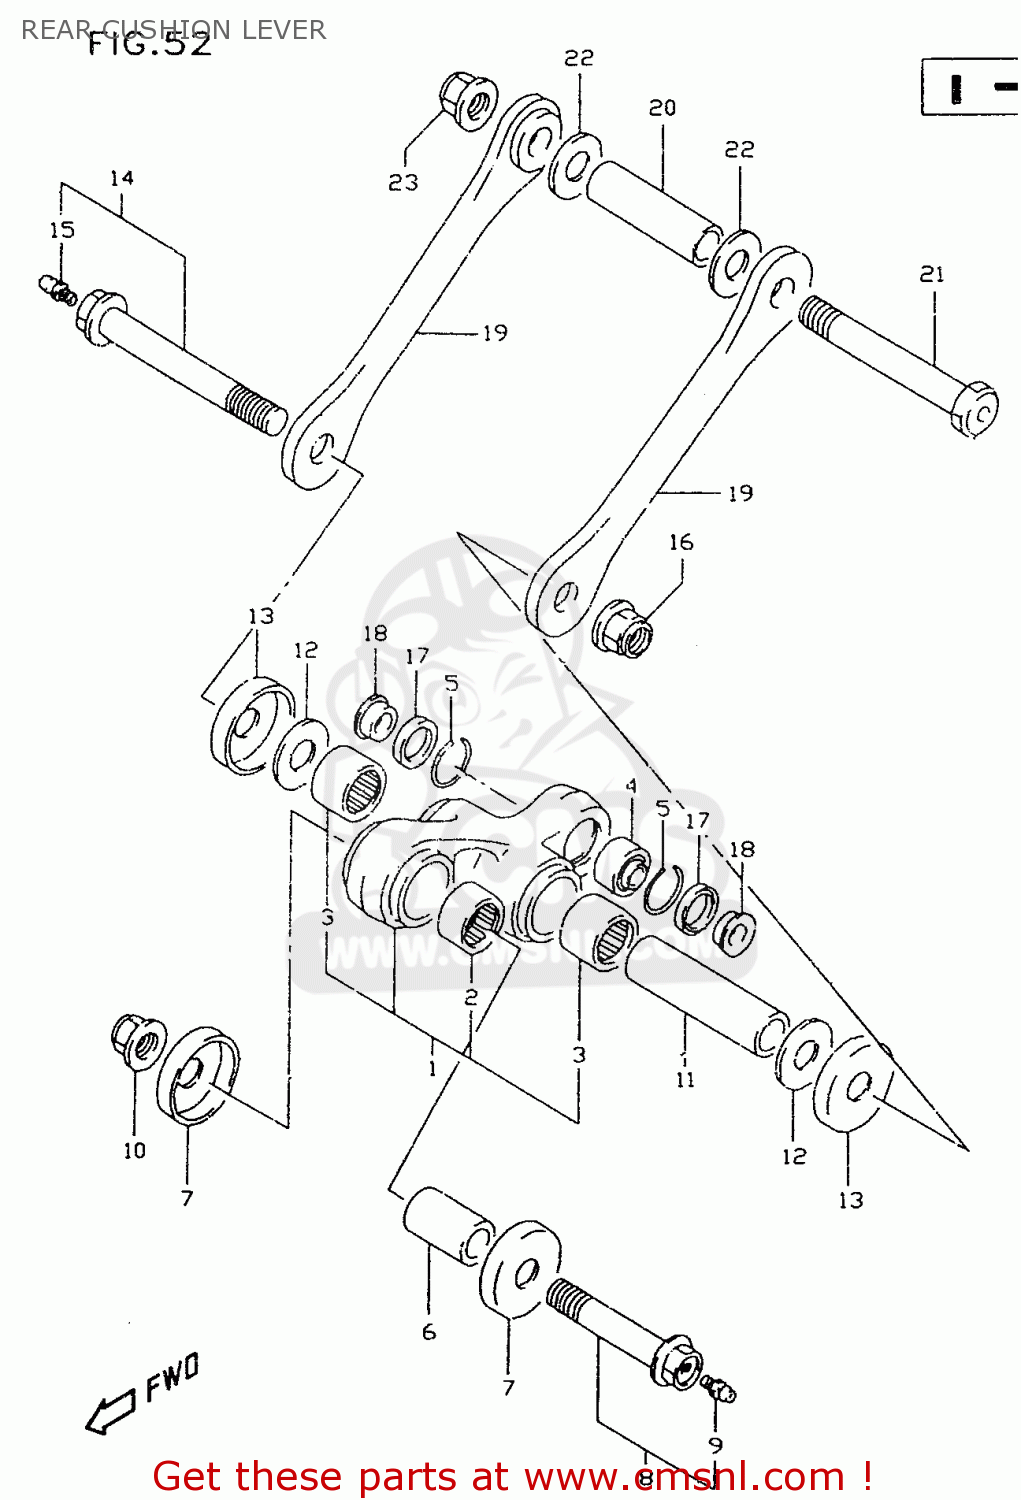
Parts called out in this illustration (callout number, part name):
1	LEVER SET,RR CUSHION
2	BEARING(20X27X32)
3	BEARING(20X27X23.5)
4	BEARING,RR CUSHION LEVER
5	RING,STOPPER
6	SPACER,RR CUSHION LEVER FR
7	SEAL,RR CUSHION LEVER FR DUST
8	BOLT,RR CUSHION LEVER FR
9	GREASE NIPPLE
10	NUT 12MM
11	SPACER,RR CUSHION LEVER CTR
12	WASHER
13	SEAL,RR CUSHION LEVER
14	BOLT,RR CUSHION LEVER CTR
15	GREASE NIPPLE
16	NUT
17	SEAL,OIL(17X24X3)
18	SPACER, REAR
19	ROD,RR CUSHION
20	SPACER,RR CUSHION ROD
21	BOLT,RR CUSHION ROD
22	WASHER
23	NUT
